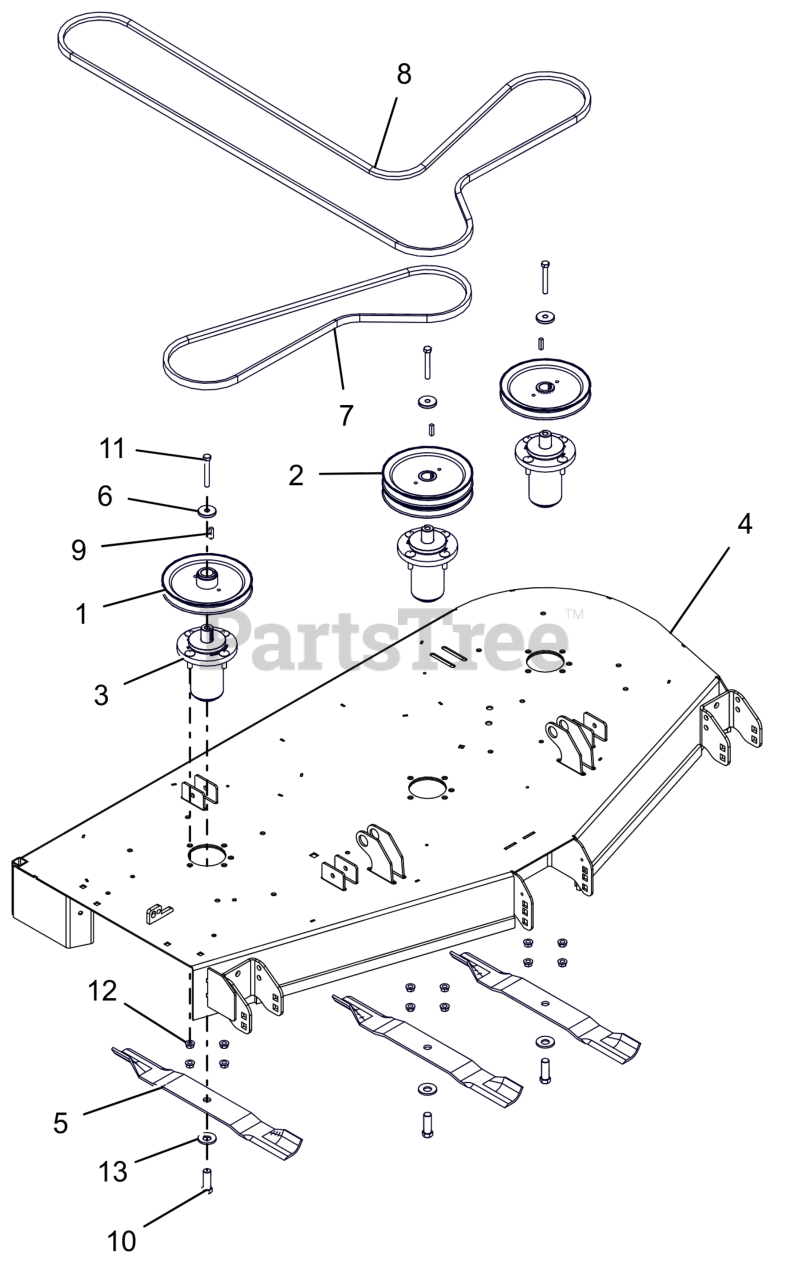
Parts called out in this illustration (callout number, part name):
1	PULLEY, V-7.50 OD X 1"ID
2	PULLEY, DOUBLE 1"X7.50"&7.50" (BLACK)
3	ASM, MAINT FREE ALUM SPINDLE
4	WLDMT, 60" CE SIDE DISCH DECK (ORANGE)
5	BLADE, 20.5"
6	RETAINER, SHEAVE
7	V-BELT, B-COGGED
8	V-BELT, HB SECTION
9	KEY, SQ .25X.25X1.00 RC 40-50
10	BLT, HEX .62-18X1.75 G8 ZCC
11	BLT, HEX .38-16X2.75 G8 ZCC
12	NUT-LK-CTR-FLG .375-16 GF ZCC
13	WSHR-BLVL .669X1.535X.138
